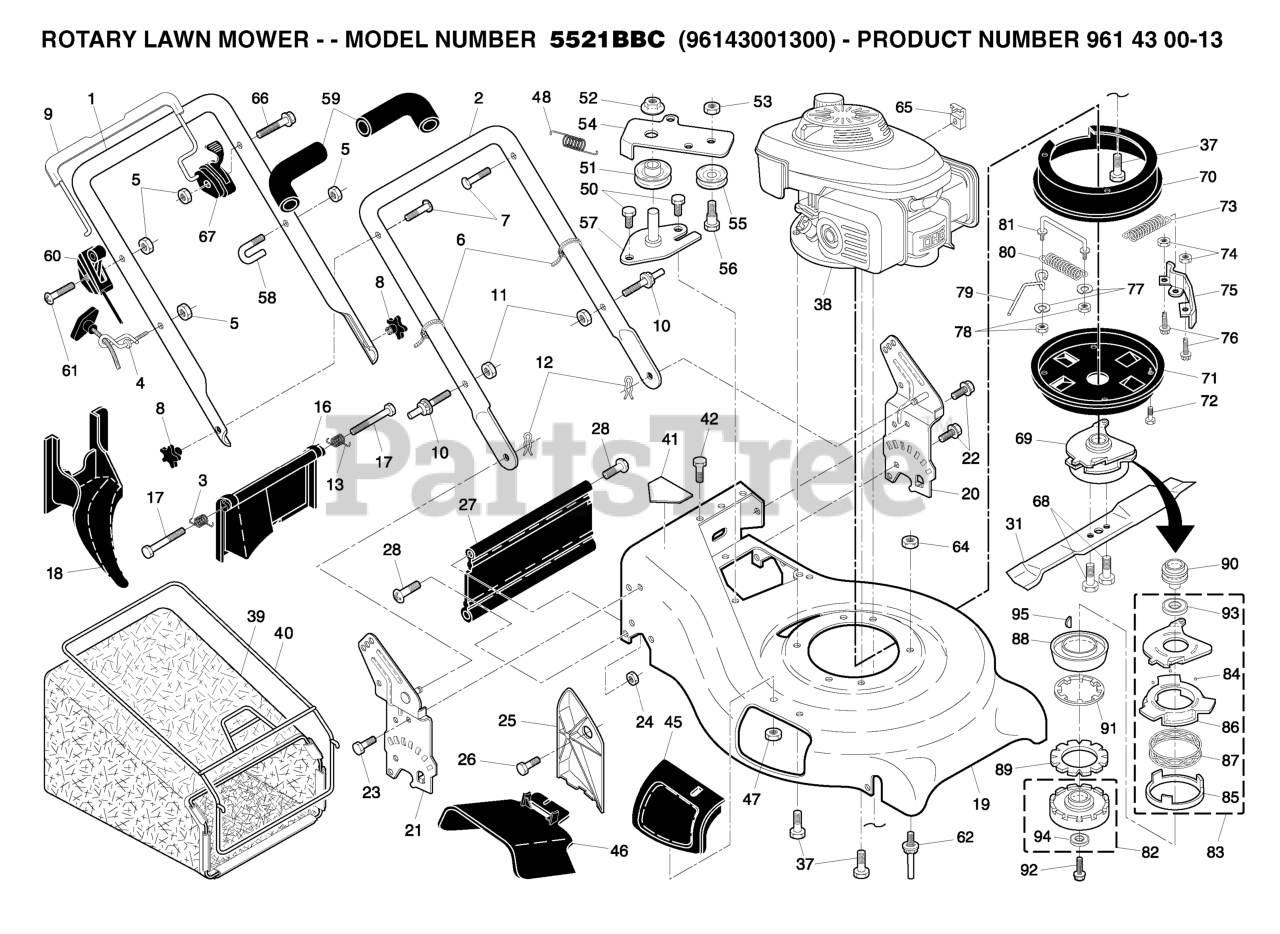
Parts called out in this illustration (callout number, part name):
1	HANDLE.UP.ASM.DSTRT/FLT
2	HANDLE LOWER
3	SPRING.LH.REAR.DOOR.21.RWGD
4	RB GUIDE.ROPE.STD.BLK.ZIN WSL
5	NUT
6	TIE GUIDE
7	BOLT, HANDLE 5/16-18X1.75
8	KNOB.HANDLE.STAR.HUSQ.GRAY
9	CONTROL BAR, AUTO-WALK
11	NUT.CENTERLOCK.5/16-
12	HAIRPIN COTTER
13	SPRING.RH.REAR.DOOR.21.RWGD
16	DOOR.REAR.PLASTIC.21.RWGD.BLAC
18	PLUG.MULCHER.RGD.21.
19	KIT.HSG.21.RGD.MC
20	BRKT.ASM.HNDL.21.RWGD.LT
21	BRKT.ASM.HNDL
22	SELF-TAPPING SCREW 5/16-18X3/4
23	BOLT, HEX HEAD 5/16-18
24	NUT.71038.31-18.HEX.NYLOCK
25	CLIPPING DEFLECTOR
27	SKIRT, REAR
28	HINGE SCREW
31	BLADE.21".BBC
37	BOLT 3/8-16X1-1/8
39	GBAG.44710247.SILVER.
40	FRAME.CATCHER.21.RGD.AG
41	DECAL HYT
45	MULCHER DOOR ASM.
46	DEFLECTOR, DISCHARGE
48	SPRING, RETURN
51	PULLEY.IDLER.V-BELT
52	NUT
53	LOCKNUT
54	ARM.IDLER
55	IDLER PULLEY
56	SHOULDER BOLT
57	BRACKET.IDLER.ASM.EZ
59	GRIP.HANDLE.FOAM.WIDE.(1 SIDE)
60	THROTTLE CONTROL
62	STUC.GUIDE.BELT.RWGD
64	NUT LOCK FLG 3/8-16 UNC
65	BRACKET.THROTTLE
67	CONTROL.BBC.HV.GRY/ORG
68	BOLT.BLADE
70	COVER.BELT.BBC.AW.TOP
71	COVER.BELT
72	TAPPING SCREW
73	SPRING.BBC
74	NUT T
75	BRAKE, CLUTCH
76	BOLT
79	BELT.GUIDE.BBC
80	SPRING.LINK.BBC
81	LINK.TORQUE.BBC
82	HOLDER.ASM.BLADE.HONDA.
83	BALL.CONTROL.PLATE.ASSY.BBC.MO
84	BALL.STEEL
85	PLATE.SPRING.HOOK
86	PLATE.BRAKE
87	SPRING BALL PLATE
88	DISC.DRIVE
89	DISK.DRIVEN
90	PULLEY.DRIVE.HONDA.
91	SPRING.CLUTCH.HONDA.
92	BOLT.FLANGE
93	BEARING.RADIAL BALL#6006
94	BEARING RAD. BALL#6204
95	KEY.WOODRUFF.16X15.HONDA
